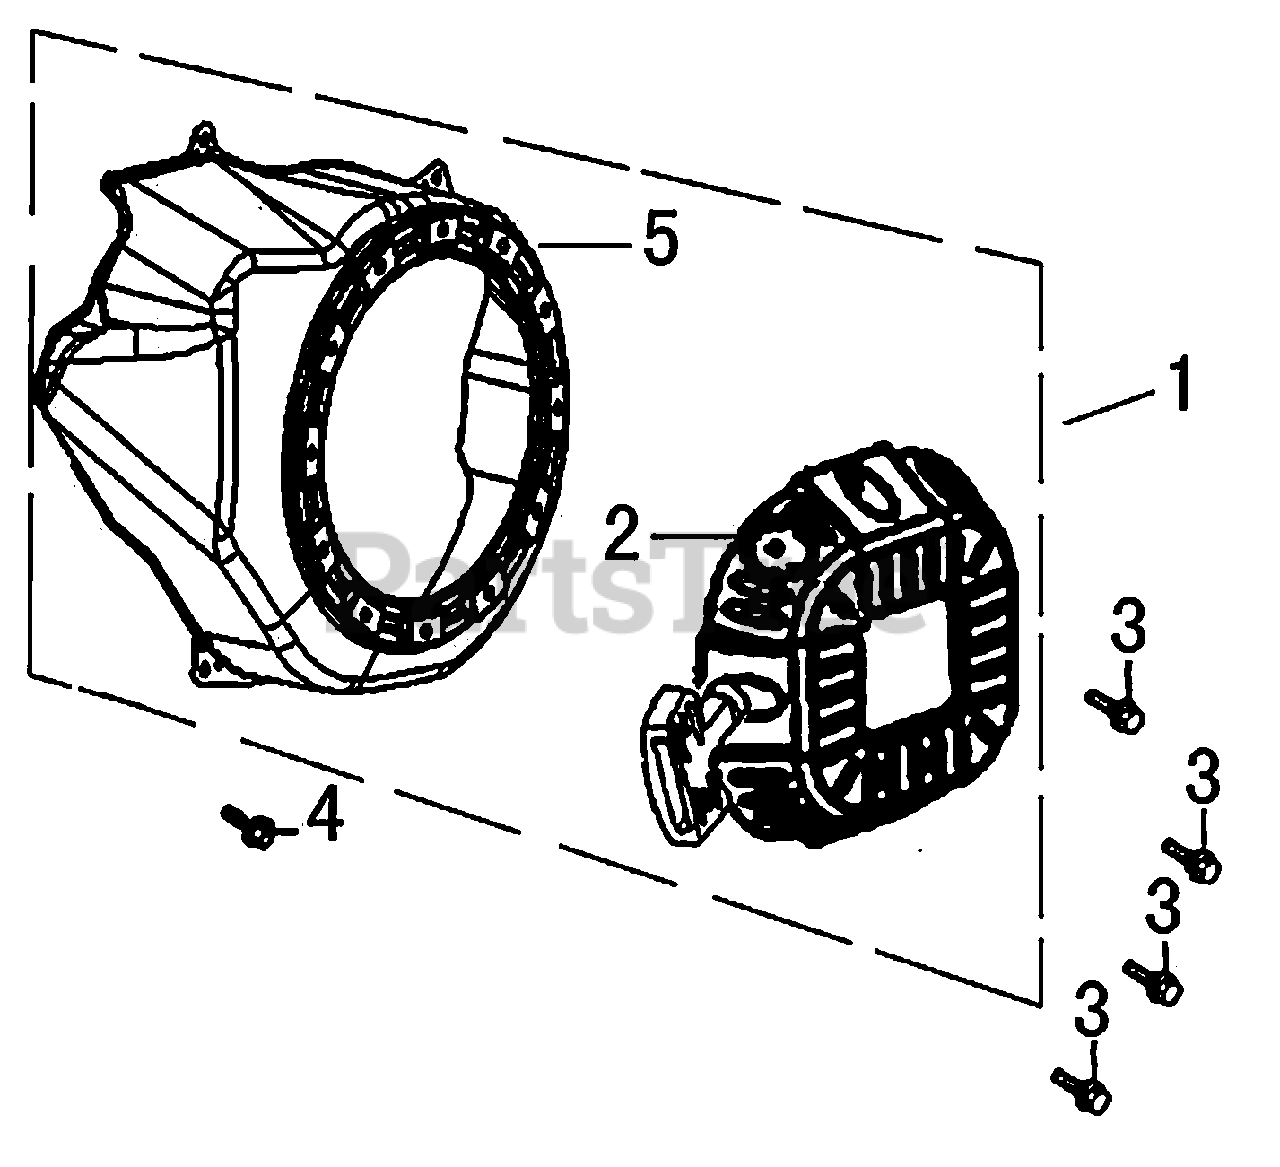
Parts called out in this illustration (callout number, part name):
1	RECOIL STARTER W/BLOWER HSNG
2	STARTER ASSY.
3	BOLT, FLANGE 6X8
4	BOLT, FLANGE 6X10
5	HOUSING, BLOWER
